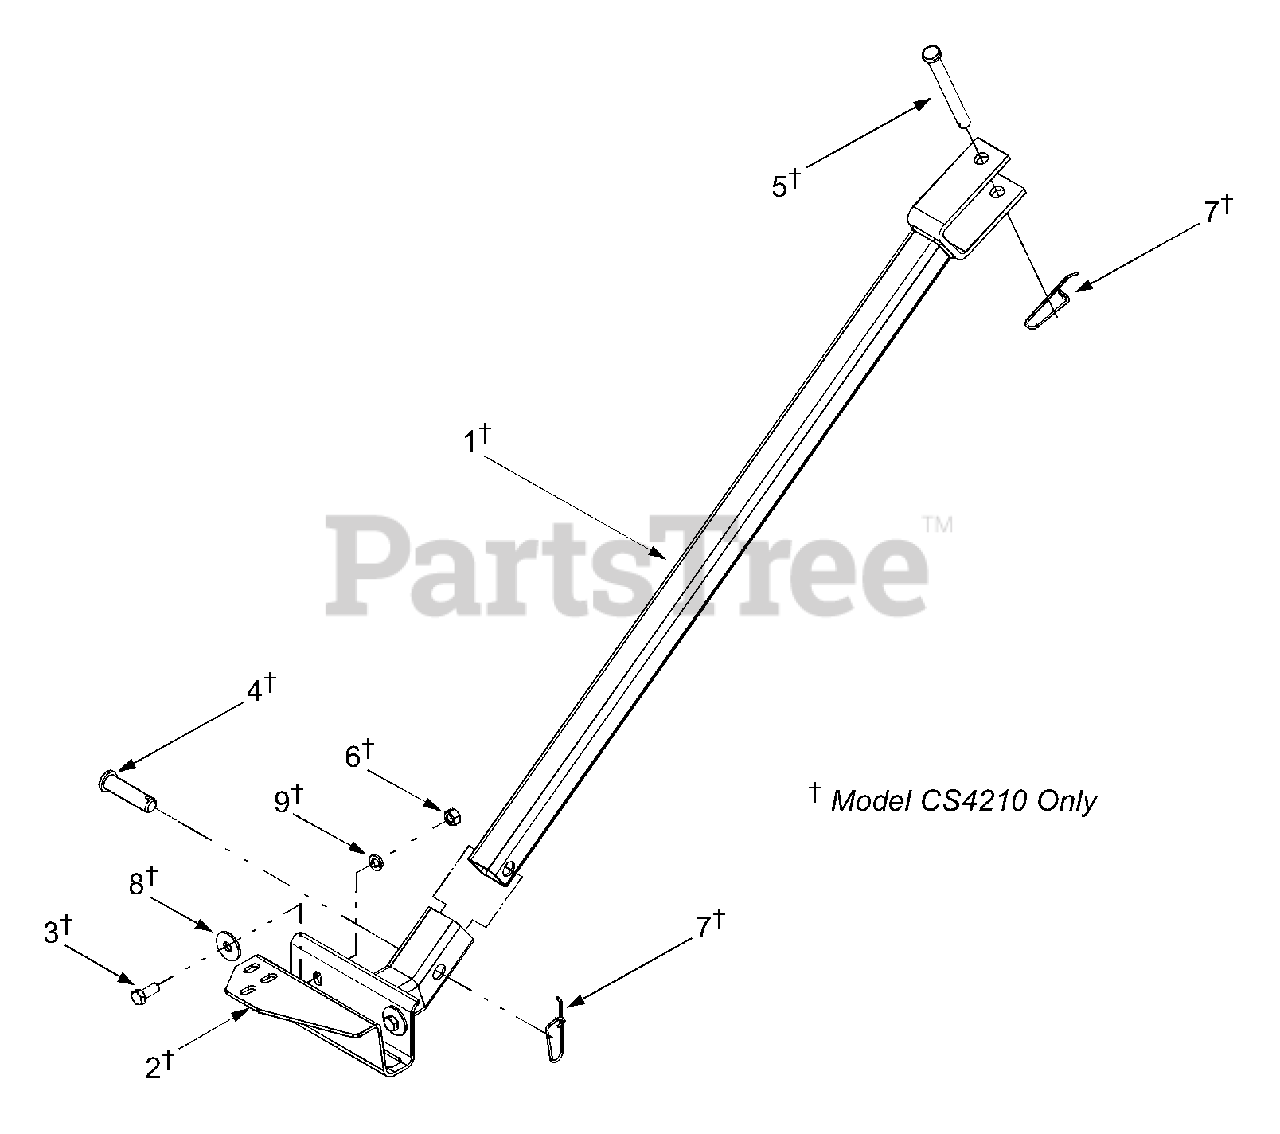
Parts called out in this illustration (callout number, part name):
3	Hex Cap Screw, 3/8-16 x .88
4	Clevis Pin, .625 x 2.4
5	Clevis Pin, .50 x 4.62
6	Hex Nut, 3/8
7	Spring Pin
8	Flat Washer, .411 x 1.25 x 1.0
9	Lock Washer, 3/8
